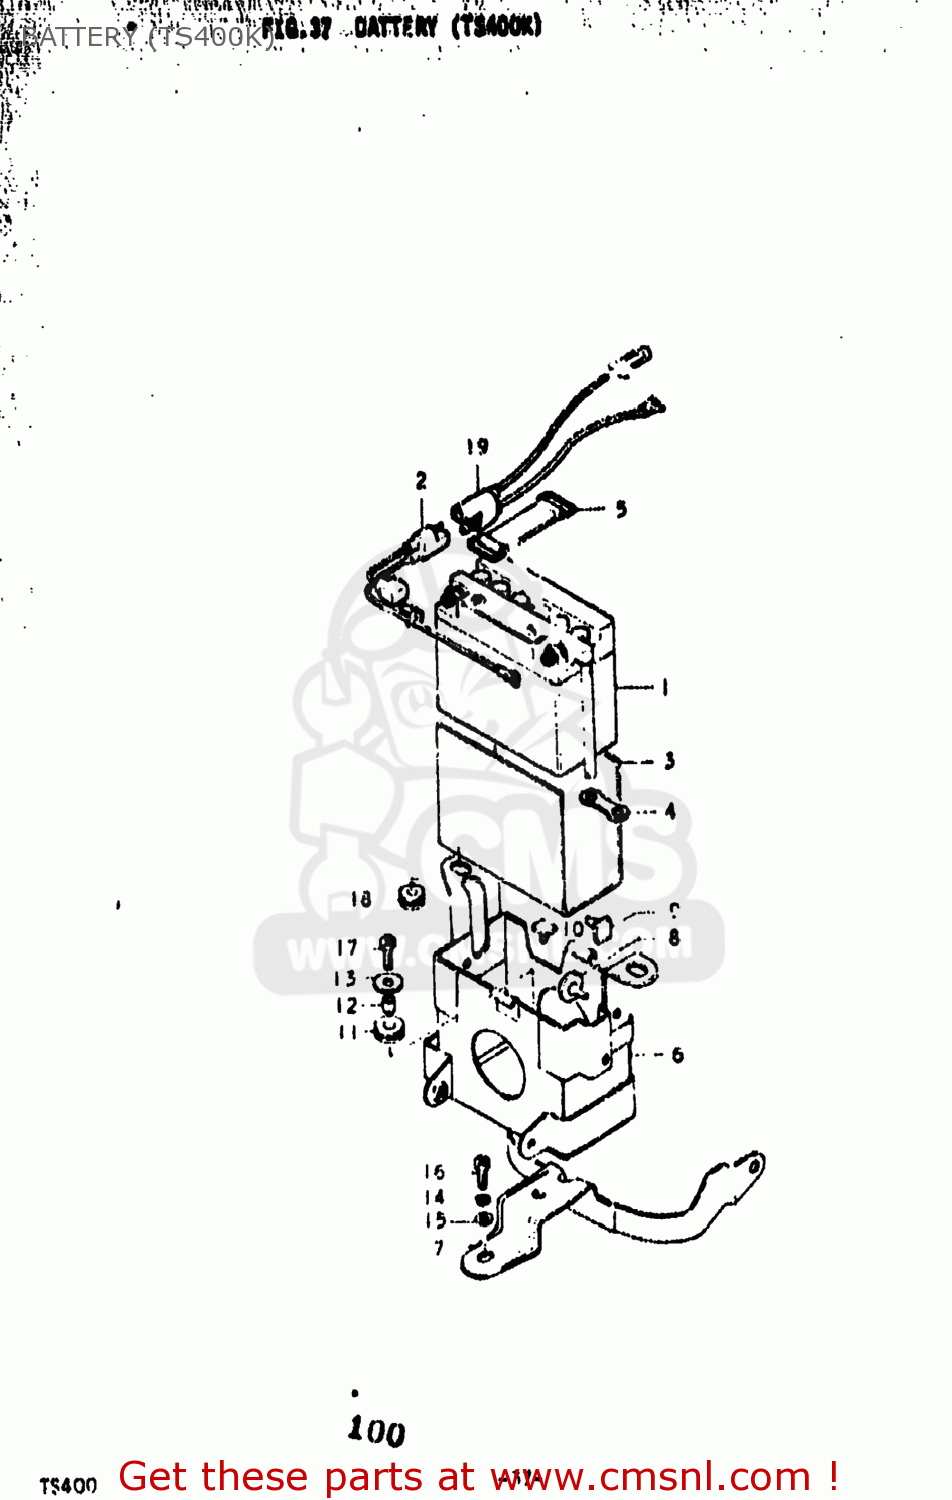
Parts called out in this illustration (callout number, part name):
1	BATTERY ASSEMBLY (12V)
2	CABLE,BATTERY
3	CUSHION,BATTERY
4	CLAMP
5	BAND
6	HOLDER,BATTERY
7	GRIP,FRAME HANDLE,LEFT
8	CUSHION
9	CUSHION
10	CUSHION
11	CUSHION
12	SPACER (7X9X7)
13	WASHER (6.5X20X1.2)
14	LOCK WASHER
15	WASHER
16	SCREW(6X14)
17	BOLT(6X20)
18	CUSHION
19	WIRE,BATTERY LEAD
